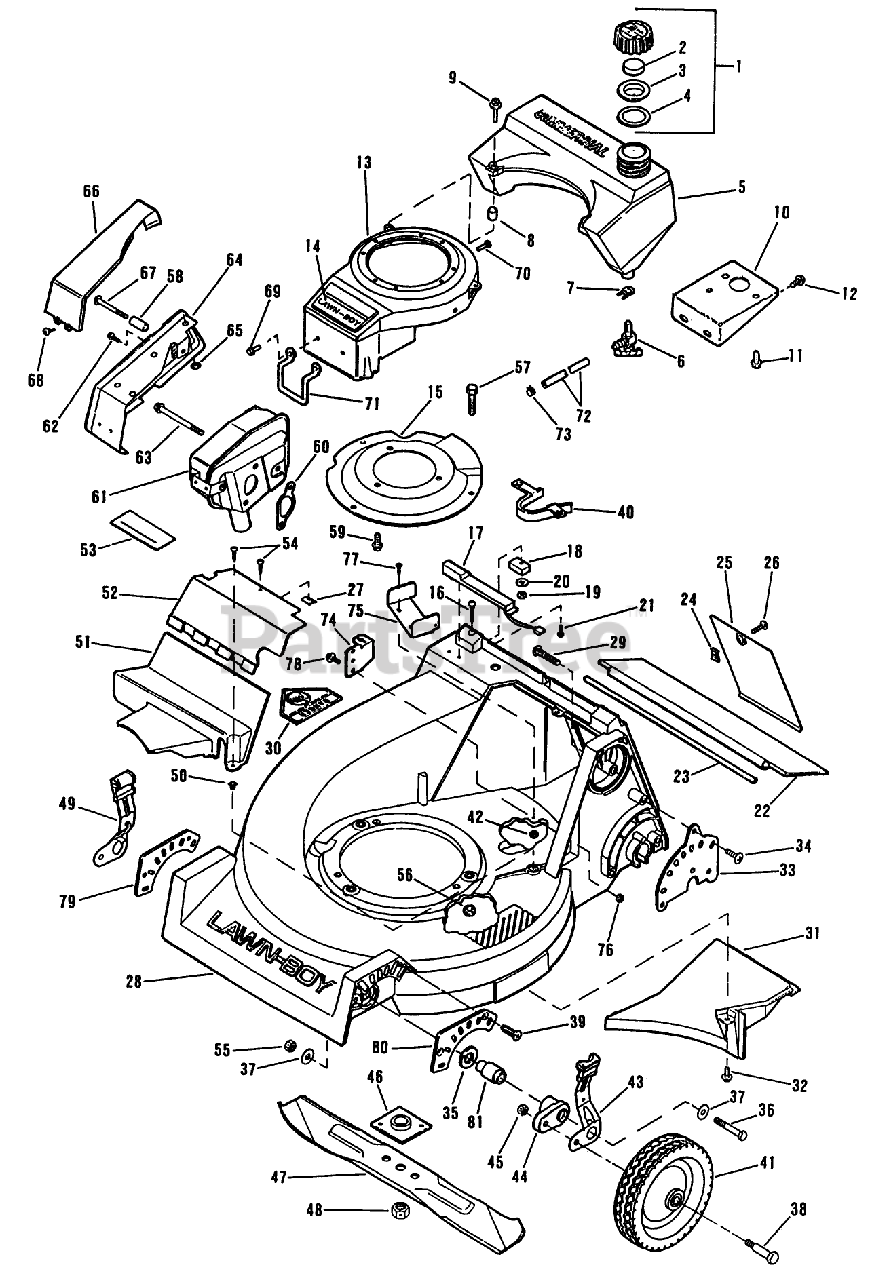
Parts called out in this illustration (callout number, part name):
1	CAP AY - F/OIL SM
2	BAFFLE - FOAM SM
4	GASKET-FUELCAP SM
6	VALVE&SCREEN SM
7	CLAMP - HOSE S
8	SPACER SM
9	SCREW - SEMS SM
14	APPLIQUE SM
15	PLATE SM
24	SPEED NUT LARSON
25	DOOR-ACCESS ELECT.
26	SCREW-CROSS RECESS
27	NUT-SPEED
31	CHUTE BAFFLE NYL
33	PLATE HGT CMS
34	SCREW-BHTF
37	WASHER-PLAIN
41	WHEEL/TIRE ASM
42	NUT C/LOCK E
43	KNOB & SPRING CMS
44	ARM HGT ADJ *BLACK
45	NUT-JAM, LOCKING
46	PLATE AND COLLAR ASM
48	NUT-BLADE
49	KNOB & SPRING CMS
50	NUT-CLIP
54	SCREW S
55	LOCKNUT
56	NUT-LOCK F
57	SCREW-HH
58	SPACER S
60	GASKET - EXH SM
62	SCREW S
63	SCREW-SEMS
64	GUARD AY-MUFFLER
65	NUT-PUSH
67	SCREW SM
68	SCREW SM
73	HOSE CLAMP SM
75	BELT GUIDELB
76	LOCKNUT E
80	Front Height Adjusting Plate-L.H.
